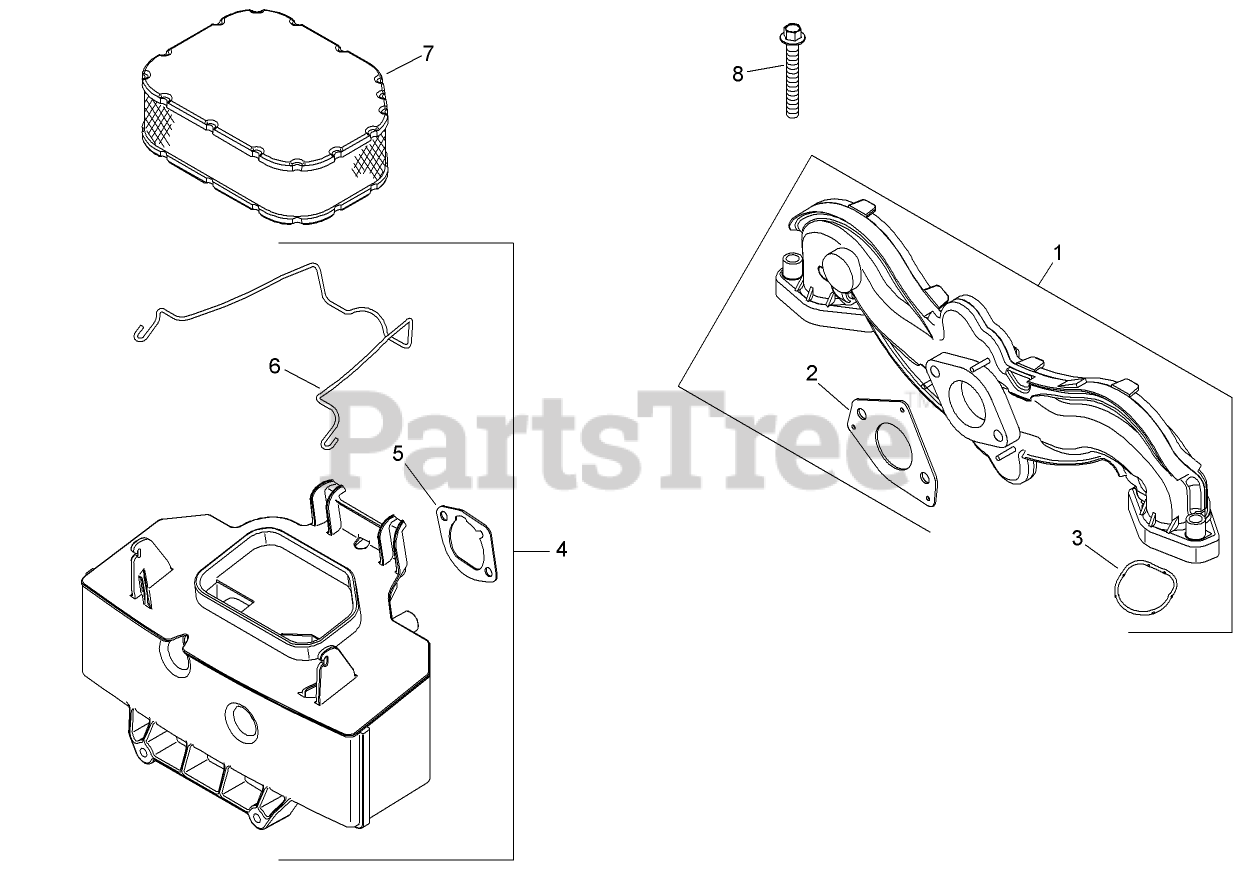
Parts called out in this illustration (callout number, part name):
1	Manifold-Intake (Includes 2-3)
2	GASKET-CARBURETOR
3	O-RING
4	AIR CLEANER BASE KIT (INCLUDES 5-6)
5	GASKET-BASE, AIR CLEANER
6	LATCH-ELEMENT, AIR CLEANER
7	ELEMENT-FILTER, AIR
8	SCREW-FLANGE (M6X1.0X40)
